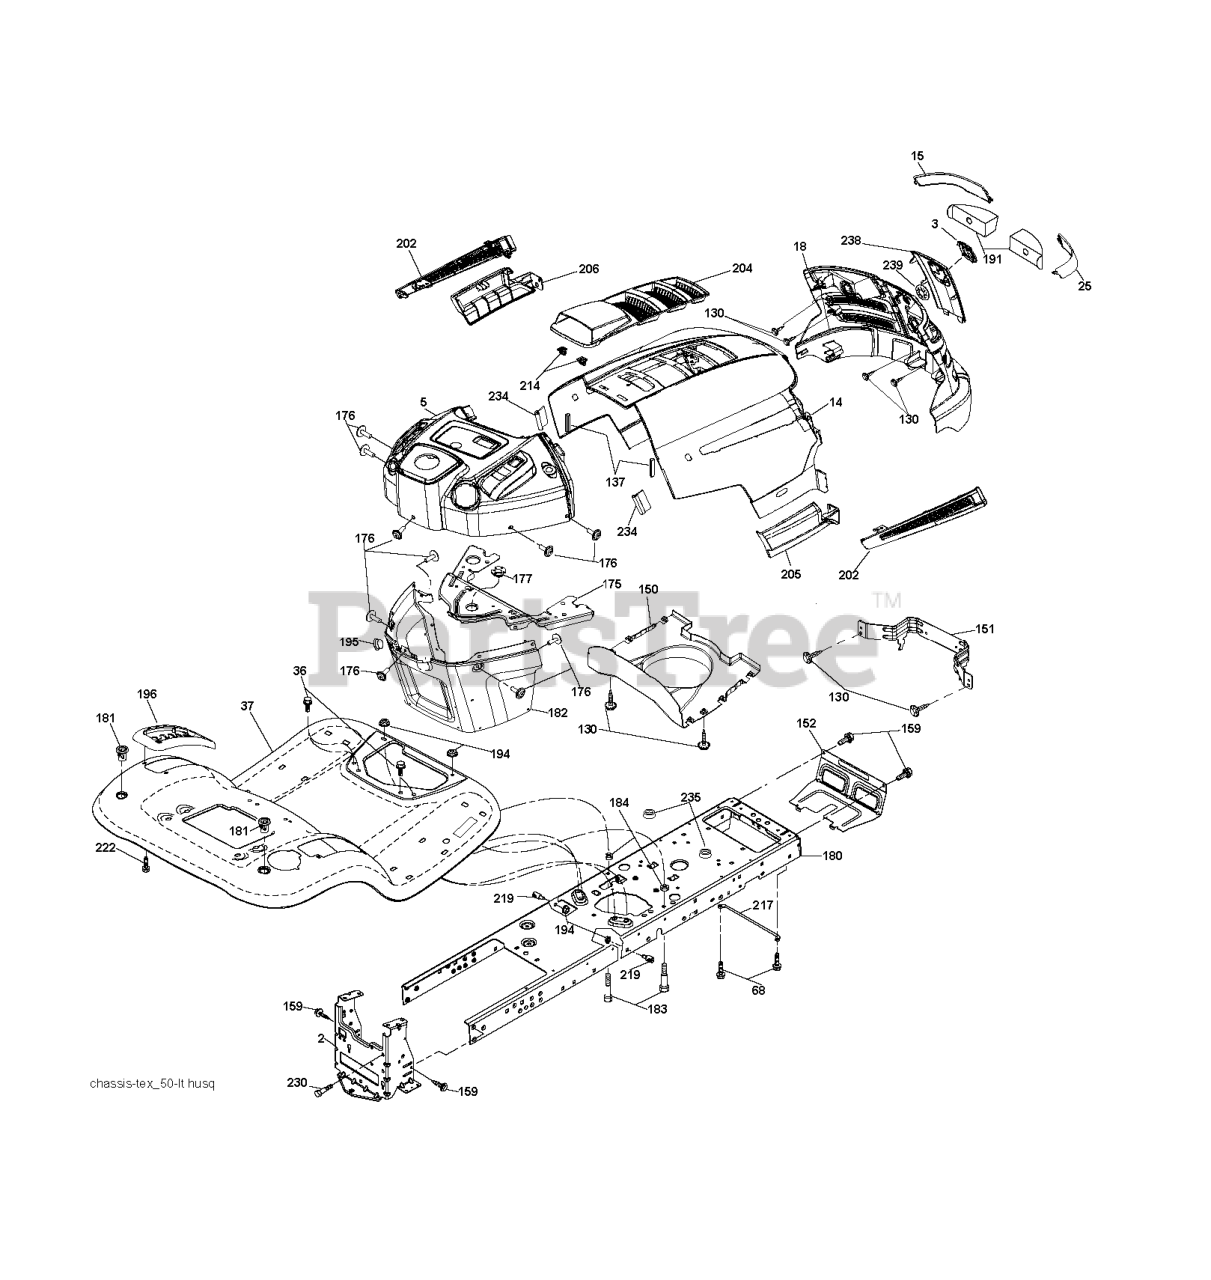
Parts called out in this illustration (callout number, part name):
2	DRAWBAR.1PC.NSTL
3	RP LOGO
5	DASH
14	HOOD
15	LENS.HUSQVARNA LT.LH
18	RP GRILLE/LENS ASM.
25	LENS.HUSQVARNA LT.RH
36	SCREW 3/8-16X3/4
68	Screw 5/16-18 x 1/2 Hex, Self Tapping 5/16-18 x 1/2
130	SCREW
137	BUMPER DASH
152	SHIELD.BROWNING/DEBRIS
159	SCREW, 3/8-16X3/4
175	CROSSMEMBER
176	SCREW.#10-24X5/8.RN.QU
177	BUSHING STEERING
180	CHASSIS.STAMPING.LT/GT
181	BUSHING.MNT.FEND.CRGO.
182	DASH LOWER
183	BOLT.5/16-18X1-1/4 FULL.THREAD
184	NUT.CENTERLOCK.5/16-
191	INSERT REFLECTIVE
194	NUT LOCK HEX FLANGE 5/16-18
195	PLUG DASH
196	CONSOLE.ASM.DECK.LIFT.
202	VENT SIDE HOOD RH
203	VENT SIDE HOOD LH
204	VENT TOP HOOD
205	SKIRT SIDE RH
206	SKIRT SIDE LH
214	CLIP.RETAINER.TINNER.
217	ROD PIVOT CHASSIS/HOOD
219	STUD.FASTNER.W/ANTI-ROTATE
222	SCREW.1/4-20X5/8
230	SHOULDER BOLT 5/16-18TT
234	BUMPER.HOOD.TEX.HUSQVARNA
235	SPACER FENDER
238	TRIM
